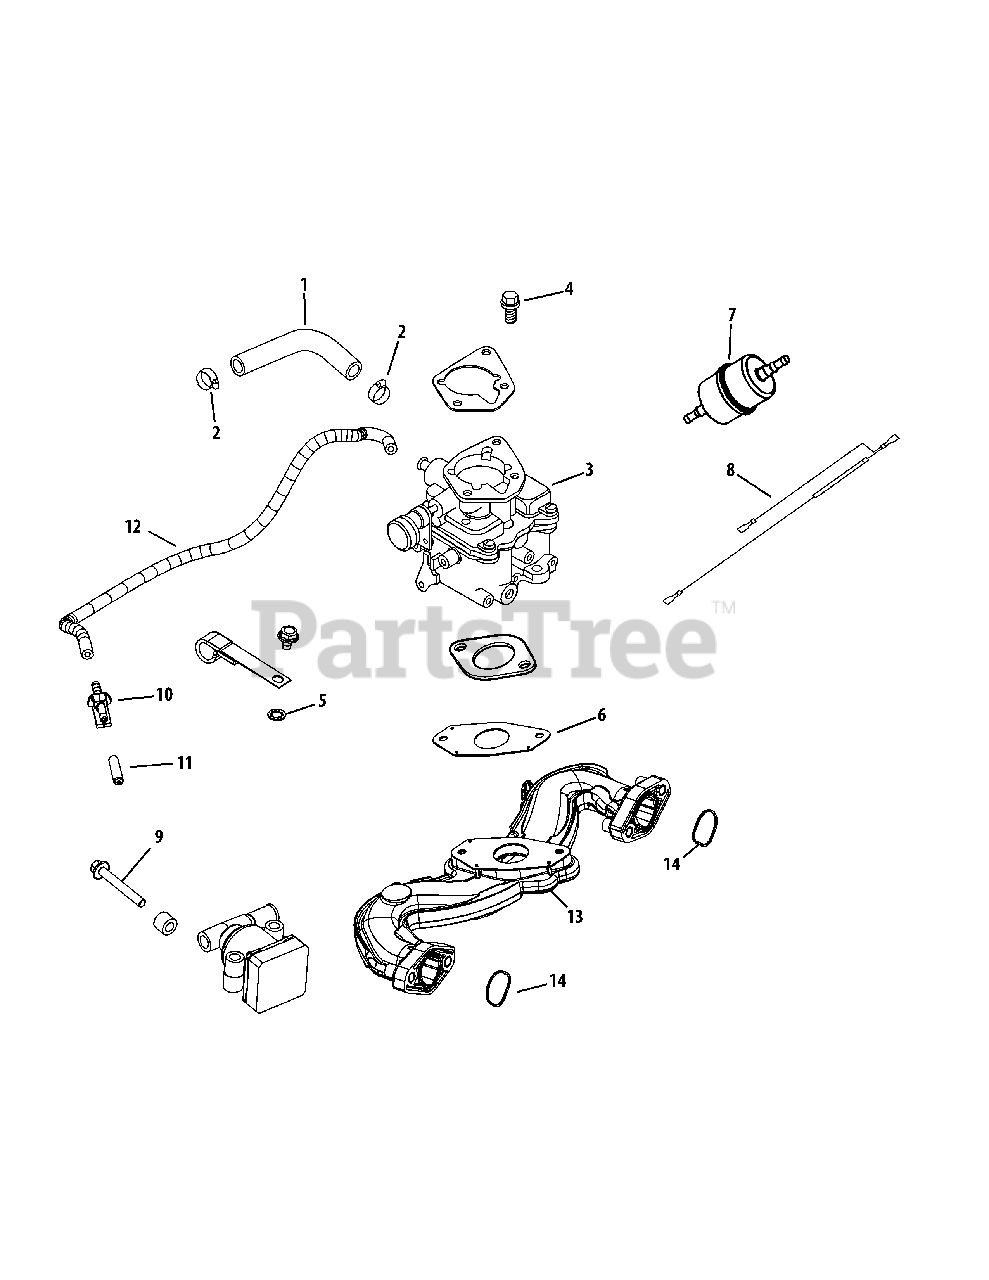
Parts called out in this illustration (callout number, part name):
1	Low Permeation Fuel Hose, 24"
3	Carburetor Kit w/ Gaskets
4	Flange Screw, M6 x 1.0 x 25
5	Internal Tooth Lock Washer, 1/4
6	Carburetor Gasket
7	Fuel Filter
9	Flange Screw, M6 x 1.0 x 40
10	Evaporative Connector
12	Evaporative Hose, 20"
13	Intake Manifold Kit
14	Intake Port O-Ring
